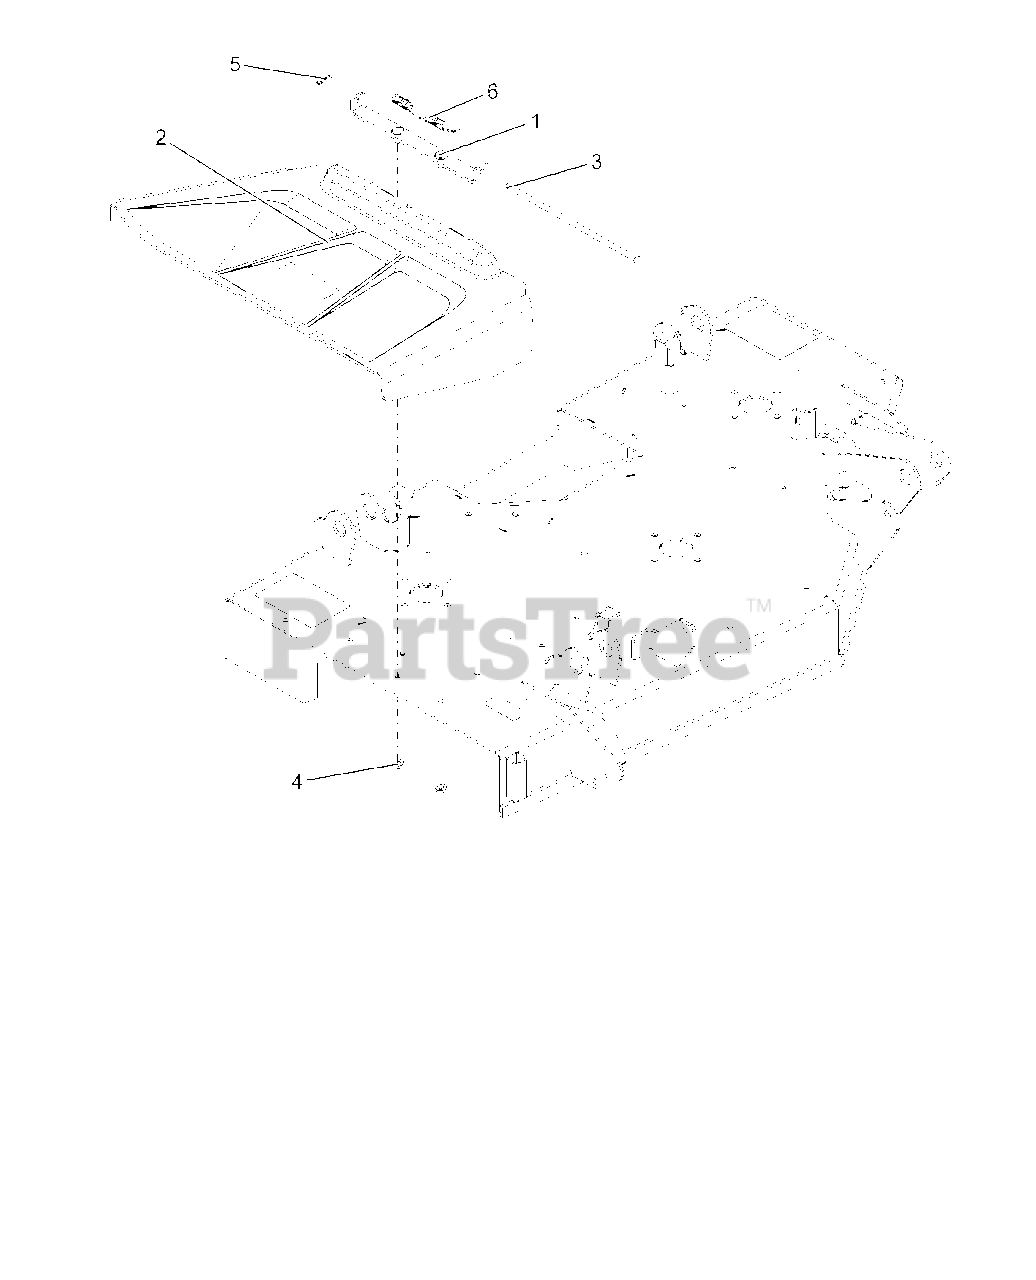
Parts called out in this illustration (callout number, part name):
1	WLDMT, CHUTE MT BRKT
2	CHUTE, SIDE DISCHARGE
3	PIN, 5/16 X 10.5
4	@NUT-LK-TOP-FLG .31-18 YWZC
5	PIN-HAIR INT .08X.18X1.18 YWZC
6	SPRING-TORSION
